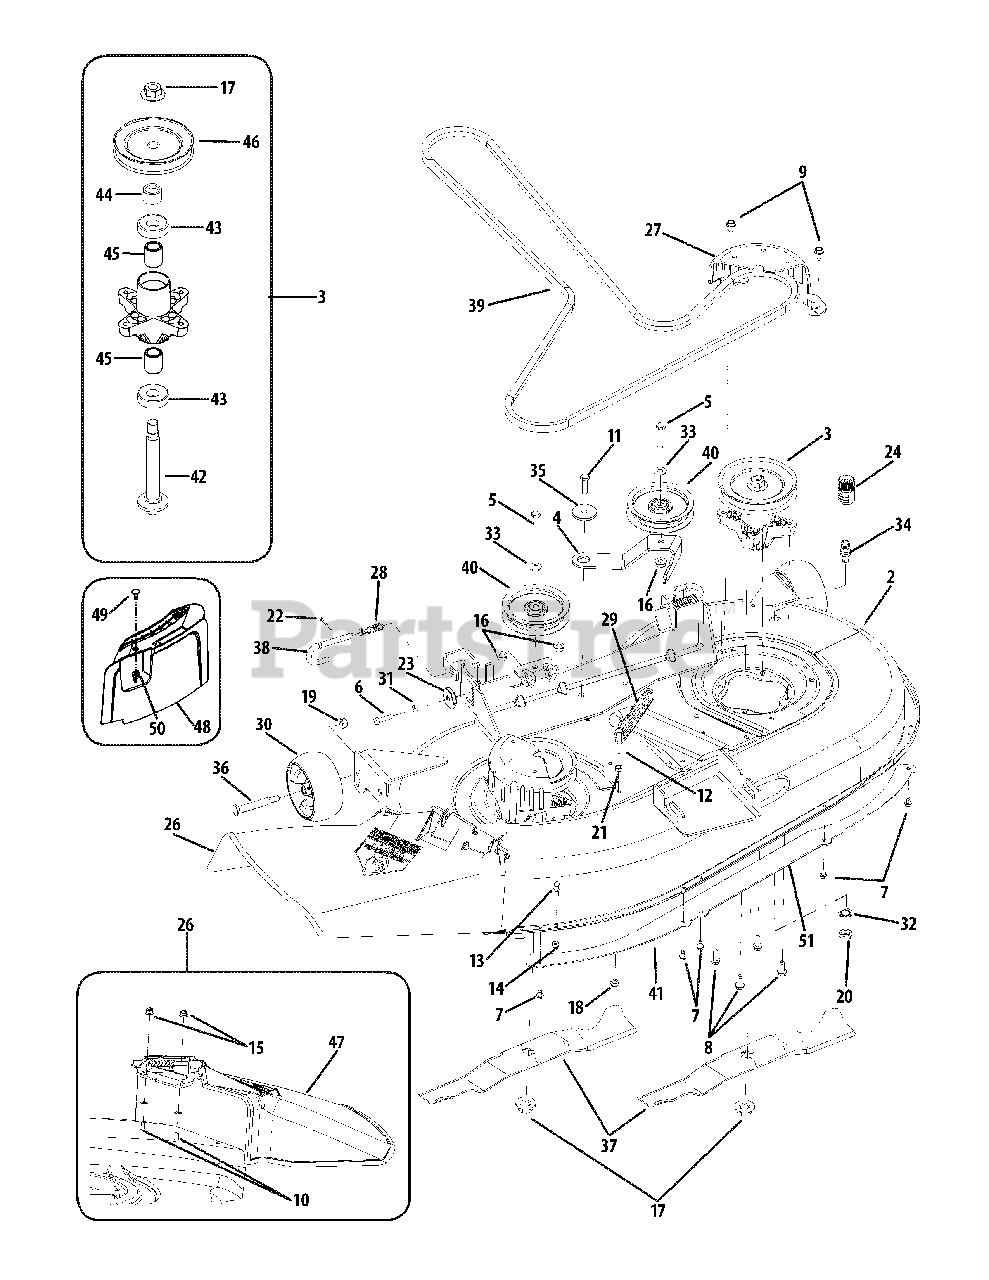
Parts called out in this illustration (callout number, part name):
3	Spindle Assembly
5	Hex Cap Screw, 3/8-16 x 1.75
6	Hex Cap Screw, 5/16-18 x 1.25
7	Hex Washer Head Screw, 1/4-20 x .5
8	Hex Washer Head Screw, 5/16-18 x .75
9	Hex Washer Head Screw, 5/16-12 x .75
10	Hex Cap Screw, 1/4-20 x .62
11	Hex Cap Screw, 3/8-16 x 1.25
12	Hex Cap Screw, 5/16-18 x 1.75
13	Grass Catcher Pin, 1/4-20
14	Hex Insert Lock Nut, 1/4-20
15	Hex Insert Flange Lock Nut, 1/4-20
16	Hex Insert Flange Lock Nut, 3/8 -16
17	Hex Flange Nut, 5/8 -18
18	Hex Insert Lock, 5/16-18
19	Hex Flange Lock Nut, 3/8-16
20	Hex Nut, M16-1.5
21	Hex Nut, 5/16-18
22	Cotter Pin, 1/8 x 1.25
23	Deck Adjustment Gear
24	Water Nozzle Adapter
25	Push Nut, .25 x .5
26	Discharge Chute Assembly
28	Compression Spring
29	Extension Spring, .94 Dia. x 6.74
30	Deck Ball Wheel, 5.0
31	Lock Washer, 5/16
33	Flat Washer, .38 x .93 x .11
34	Deck Water Nozzle
35	Shoulder Spacer, .884 x .19
36	Shoulder Screw, .5 x 2.5 x 3/8 -16
37	Blade, 3 in 1, 21.23
38	Deck Hanger Rod
39	V-Belt Type A Sec x 114.1
40	Idler Pulley, 4.25 Dia
42	Spindle Shaft, 5.75
43	Ball Bearing
44	Spacer, .820 x 1.15 x .73
45	Spacer, .8 x 1.10 x 1.322
46	Deck Pulley, 6.3 Dia
47	Chute Deflector
49	Carriage Screw, 1/4-20 x .62
50	Wing Nut, 1/4-20
